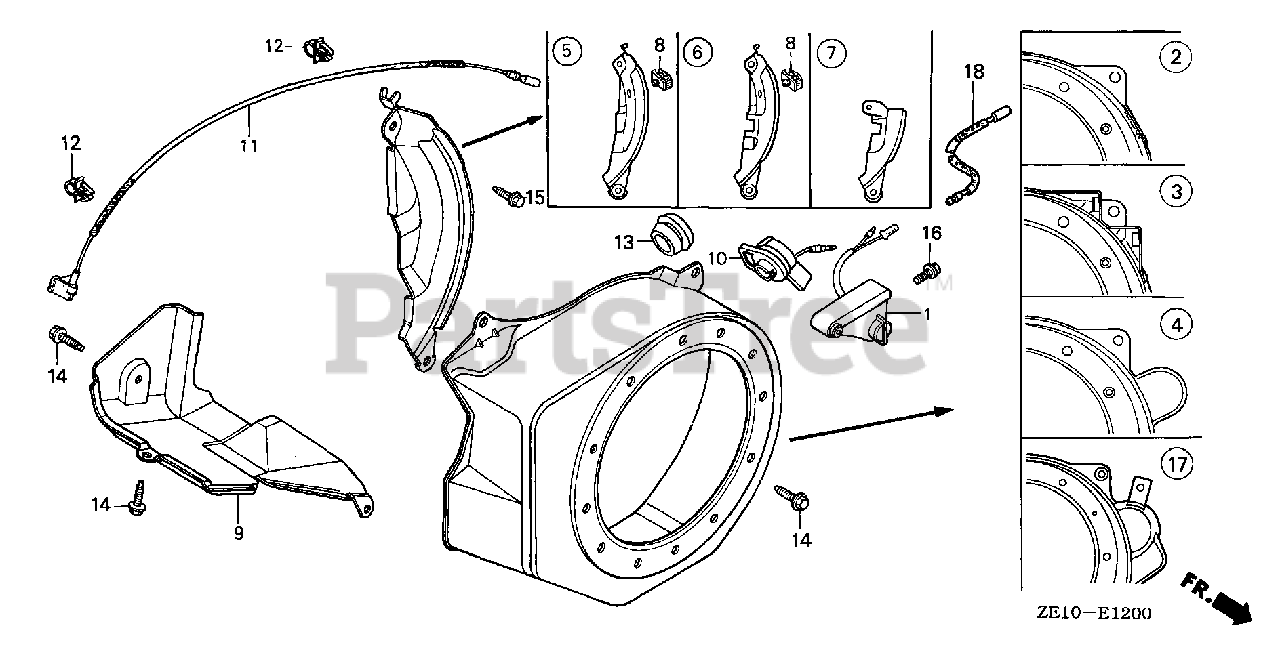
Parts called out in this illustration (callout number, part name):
1	ALERT UNIT, OIL
3	COVER, FAN *R8* (OIL ALERT) (BRIGHT RED)
6	PLATE, SIDE (ALERT & LAMP)
8	CLAMP, CORD
9	SHROUD
11	WIRE, STOP SWITCH (395MM)
11	WIRE, STOP SWITCH (370MM)
12	HOLDER, STOP SWITCH WIRE
14	BOLT, FLANGE (6X12) (CT200)
15	BOLT, FLANGE (6X20) (CT200)
16	BOLT, FLANGE (6X8)
